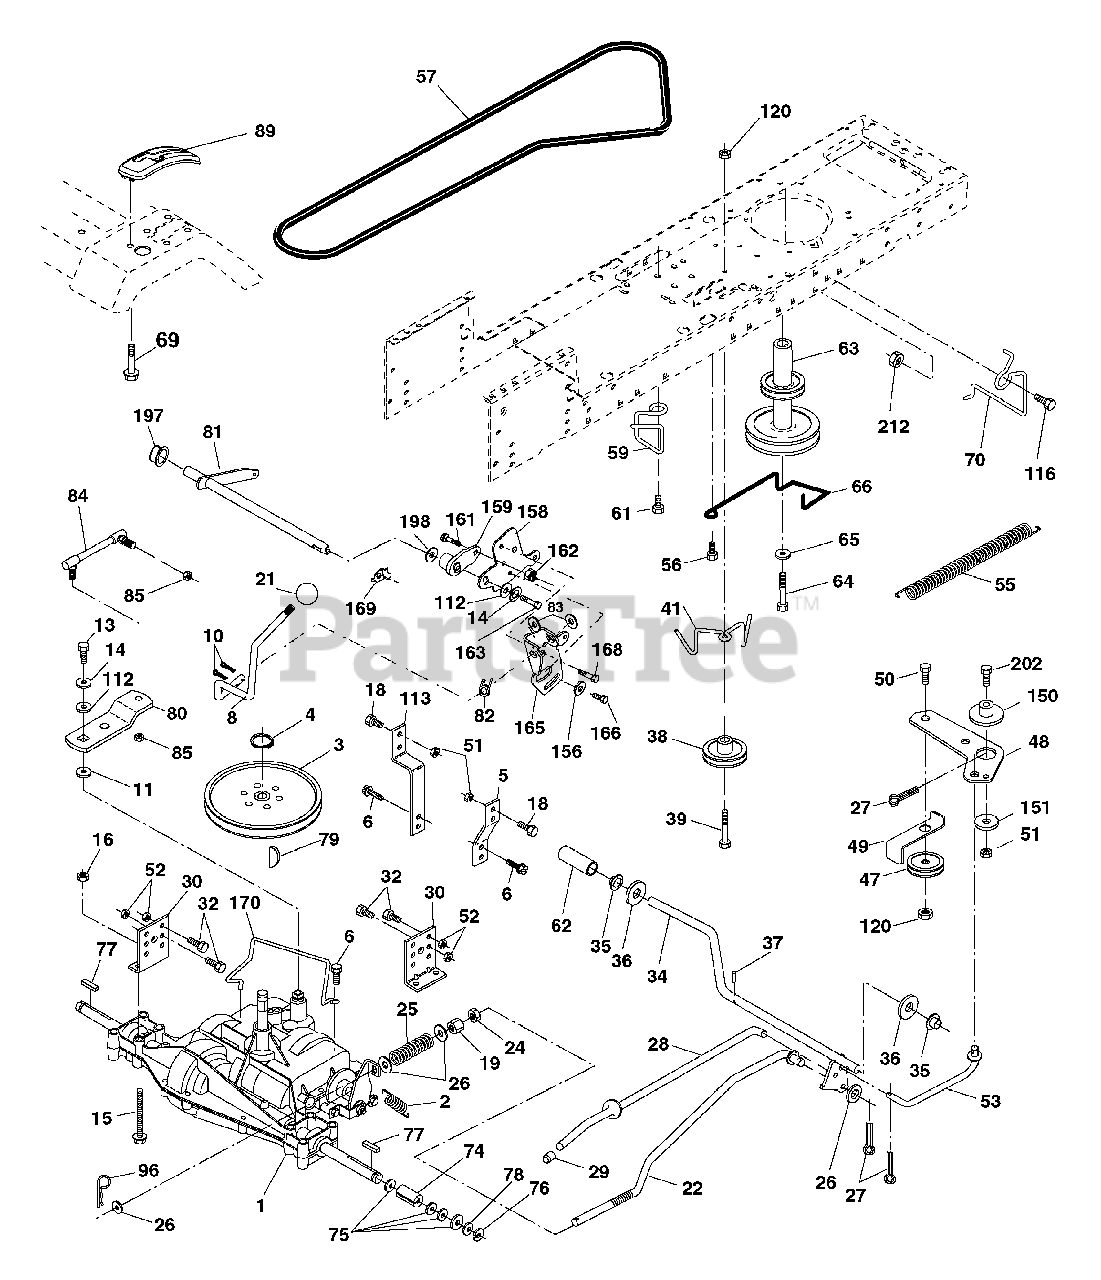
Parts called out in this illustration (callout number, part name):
2	Spring Return Brake T/a Zinc
3	Pulley Transaxle 18" tires
4	Ring Retainer # 5100-62
5	Strap Torque 30 Degrees
6	Screw Thdrol 5/16-18 x 3/4 TYT
8	Rod Shift Fender Adjust STLT
10	Pin Cotter 1/8 x 1 Cad
11	Washer Plate Shf 388 Sq Hole
13	Bolt 1/4-28 unf Gr. 8 W/Patch
14	Washer Lock Hvy Helical 1/4
15	Bolt 5/16-18 Gr. 5
16	Nut Lock Hx W/Ins 5/16-18 unc Pl
18	Bolt, Fin Hex 3/8-16 unc x 1 Gr. 5
19	Nut Lock 3/8-16 unc
22	Rod Brake Blk Zinc 26 840
24	Nut Hex Jam 3/8-16 unc
25	Spring Rod Brake 2 00 Zinc
26	Washer 13/32 x 13/16 x 16 Ga
27	Pin Cotter 1/8 x 3/4 Cad
28	Rod Brake Parking LT/YT
29	Cap Brake Parking Black
30	Bracket Mtg Transaxle
32	Bolt Hex Hd 5/16-18 unc x 3/4
34	Shaft Asm Pedal Foot
35	Bearing Nylon Blk 629 Id
36	Washer 21/32 x 1 x 16 Ga
37	Pin Roll 3/16 x 1"
38	Pulley Composite
39	Bolt Rdhd 3/8-16 x 2-3/4 Gr. 5
41	Keeper Belt Idler Flat
47	Pulley Idler V Groove Plastic
48	Bellcrank Clutch Grnd Drv Stl
49	Retainer Belt Style Spring
50	Bolt Carr. sh 3/8-16 x 1-1/2 Gr. 5
51	Nut Crownlock 3/8-16 unc
52	Nut Crownlock 5/16-18 unc
53	Link Clutch
55	Spring Return Clutch 6 75
56	Screw 3/8-16 x 1-1/4
57	V-Belt Ground Drive 95 25
59	Keeper Belt Span Ctr
61	Screw 3/8-16 x .875
62	Cover Pedal
63	Engine Pulley LT/YT
64	Bolt Hex
65	Washer Lock Hvy Hlcl Spr 7/16
66	Keeper Belt Engine Foolproof
69	Screw Hex Wsh Hi-Lo 1/4-1/2 unc
70	Guide Belt Mower Drive RH
74	Spacer Axle
75	Washer 25/32 x 1 1/4 x 16 Ga.
76	E-ring #5133-75
77	Key Square 20 x 1845/ 1865
78	Washer 25/32 x 1-5/8 x 16 Ga.
79	Key Woodruff #9 3/16 x 3/4
81	Shaft Asm Cross Tapered DA/PR 18"
82	Spring Torsion T/a
83	Washer 17/32 x 3/4 x 16 Ga.
84	Transaxle Link
85	Nut Lock Center 1/4 - 28 FNTHD
89	Console Shift STLT
96	Retainer Spring 1"
112	Washer 9/32 x 3/4 x 10 Ga.
113	Strap Torque LT
116	Bolt Rdhd Sq Neck 3/8-16 x 1
120	Nut Lock Flg. 3/8-16
150	Spacer Retainer
151	Washer 13/32 x 2 x 10 Ga.
156	Washer Srrted 5/16 ID x 1.125
158	Bracket Shift Mount
159	Hub Shift
161	Bolt Rdhd Sqnk 1/4-20 x 3/4 Gr. 5
162	Nut Crownlock 1/4-20 unc
163	Bolt Hex Fin 1/4-20 unc x 1 Gr. 5
165	Bracket Pivot Lever
166	Screw 5/16-18 x 5/8
168	Bolt Shoulder 5/16-18 x .561
169	Plate Fastening STLT/CRD
170	Keeper Belt T/A
197	Nyliner Snap-In 5/8" ID
198	Washer Nyl 7/8 Id x .105" Hyd
202	Bolt 3/8-16 x 1-3/4 Gr 5
212	Nut Hex Flg Lock
